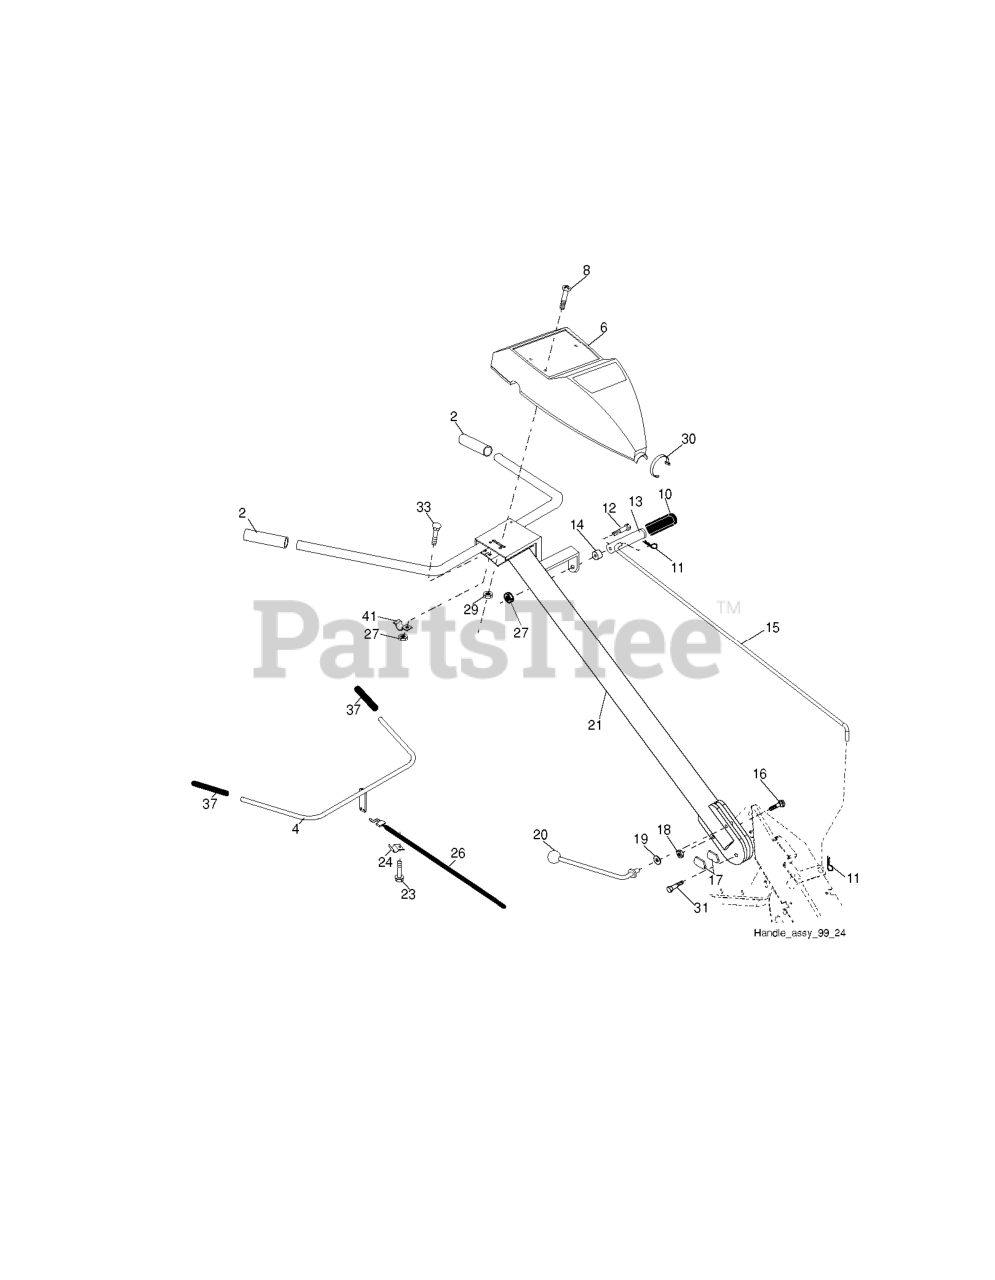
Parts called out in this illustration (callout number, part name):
2	GRIP.1X5.06
4	CONTROL BAR ASSY
6	RP PANEL, CONTROL
8	SCREW.PNHD.10-24
10	GRIP T
11	RETAINER M
12	SHOULDER BOLT ST
13	HANDLE.SHIFT.TILLER
14	GROMMET.RUBBER.CRT.TILLER
15	SHIFT ROD CRT
16	BOLT D
17	LOCK.HANDLE.CRT
19	WASHER CRT
20	LEVER.LOCK.CRT
21	REPL BY 532 1805-17
23	TAPPING SCREW
24	CONDUIT.CLIP.PLATED
26	CABLE.CLUTCH
27	NUT T
29	NUT **
30	TIE CABLE CRT
31	BOLT.PIVOT
37	GRIP BAR CRT(1)
41	CLAMP.BAR.CRT.BLACK
